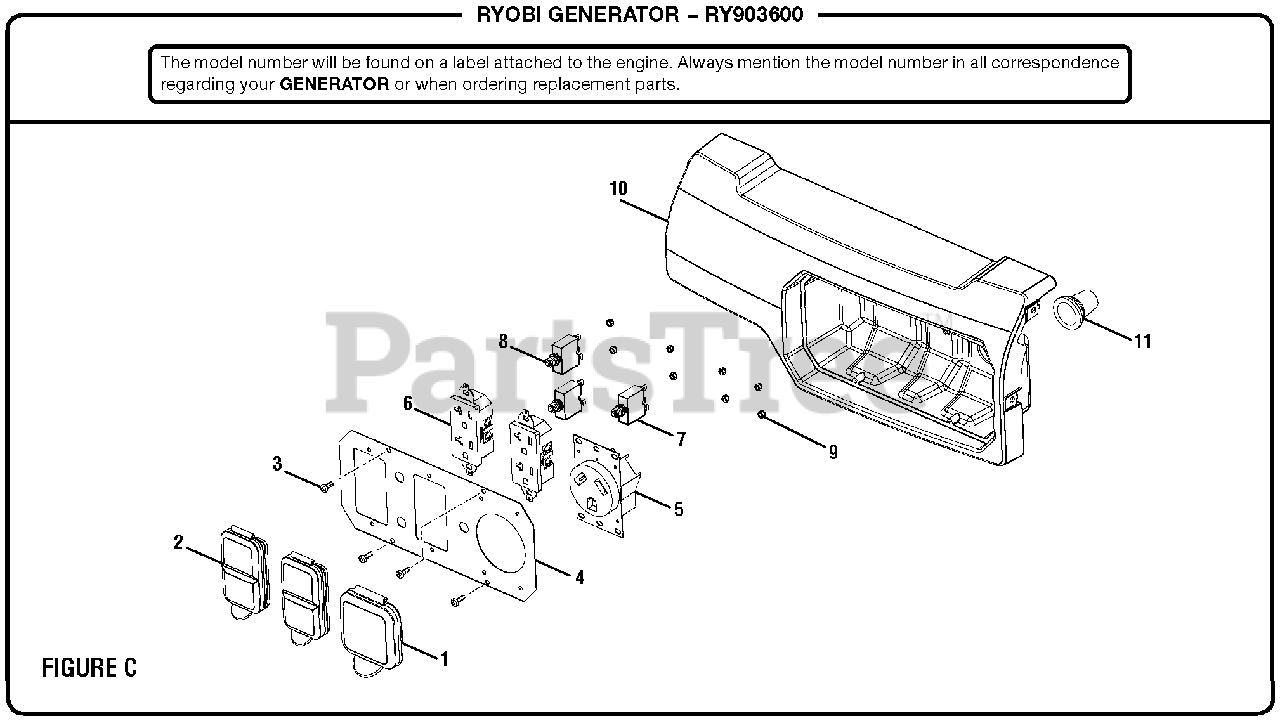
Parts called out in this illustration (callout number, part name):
1	Outlet Cover
2	Duplex Outlet Cover
3	Screw (M4.2 x 12 mm Pan Hd.)
4	Front Panel
5	Receptacle (120V)
6	Duplex Receptacle (120V)
7	Circuit Breaker (30 Amp)
8	Circuit Breaker (20 Amp)
9	Lock Nut (M4)
10	Control Box (Back Panel)
11	Rubber Boot
